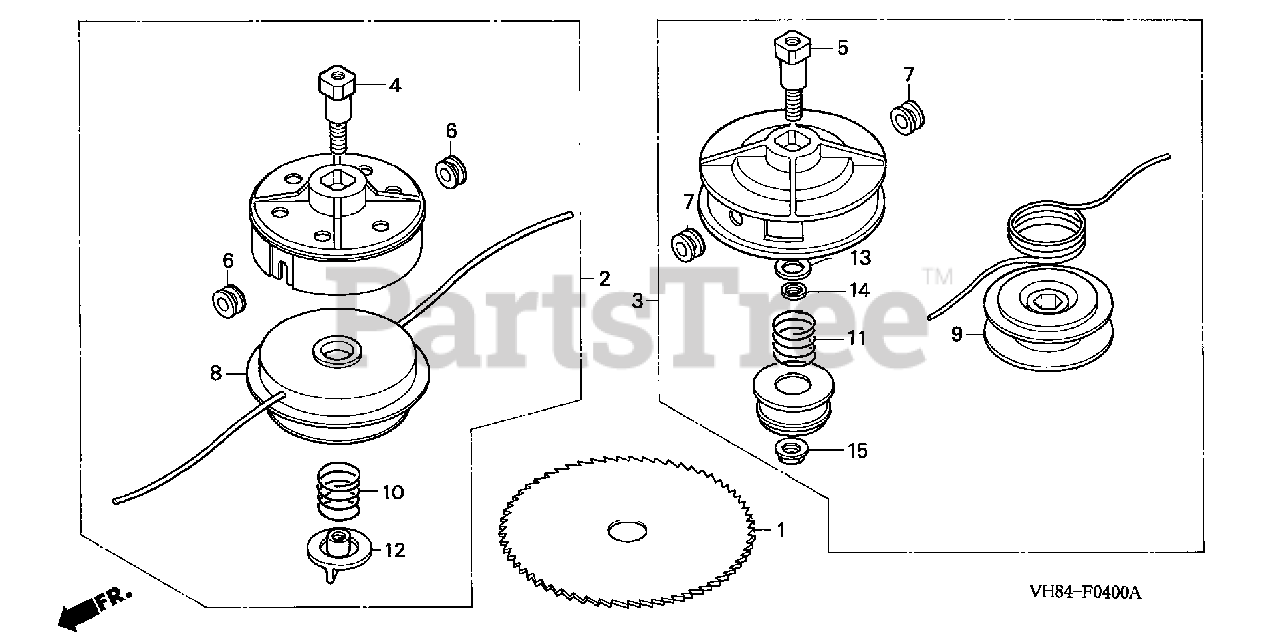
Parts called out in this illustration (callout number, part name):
3	CUTTER ASSY., NYLON
5	SHAFT (10X1.25) (LH)
11	SPRING
14	DRIVE (OUTER)
15	CAM (INNER)
